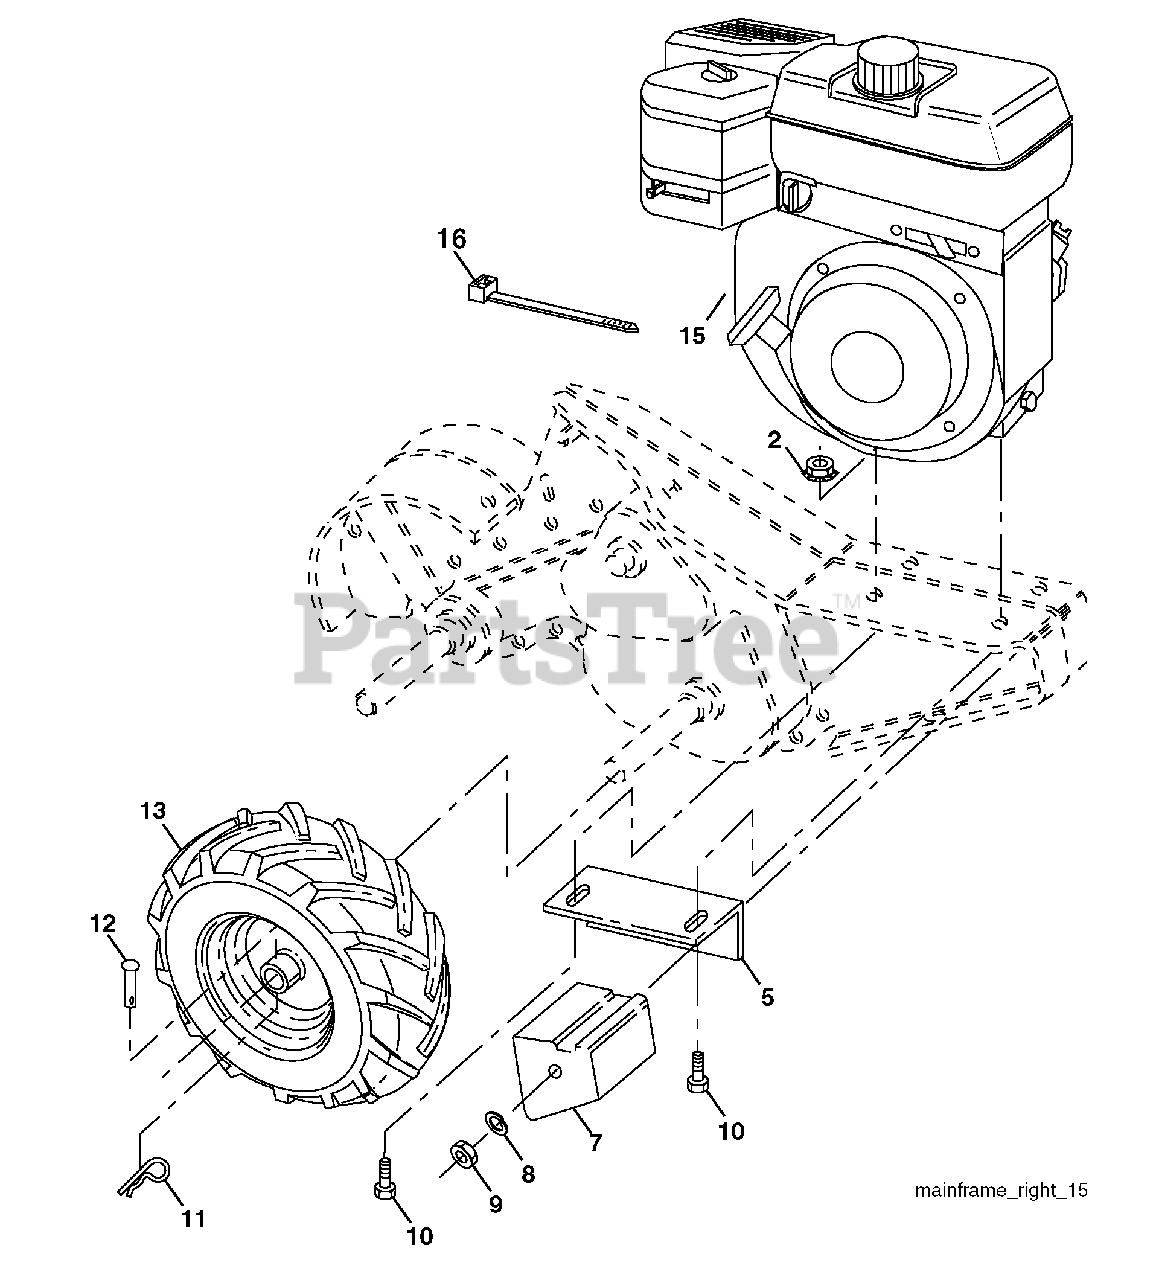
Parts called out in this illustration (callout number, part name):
2	Nut, Hex Flange
5	Bracket, Reinforcement
7	Counter Weight, R.H.
8	Washer, Lock 3/8
9	Nut, Hex 3/8-16
10	Bolt, Hex 5/16-18 x 1-1/2
11	Clip, Hair pin
12	Rivet, Drilled
13	Tire
13	Rim
13	Tire Valve
16	Tie Cable
